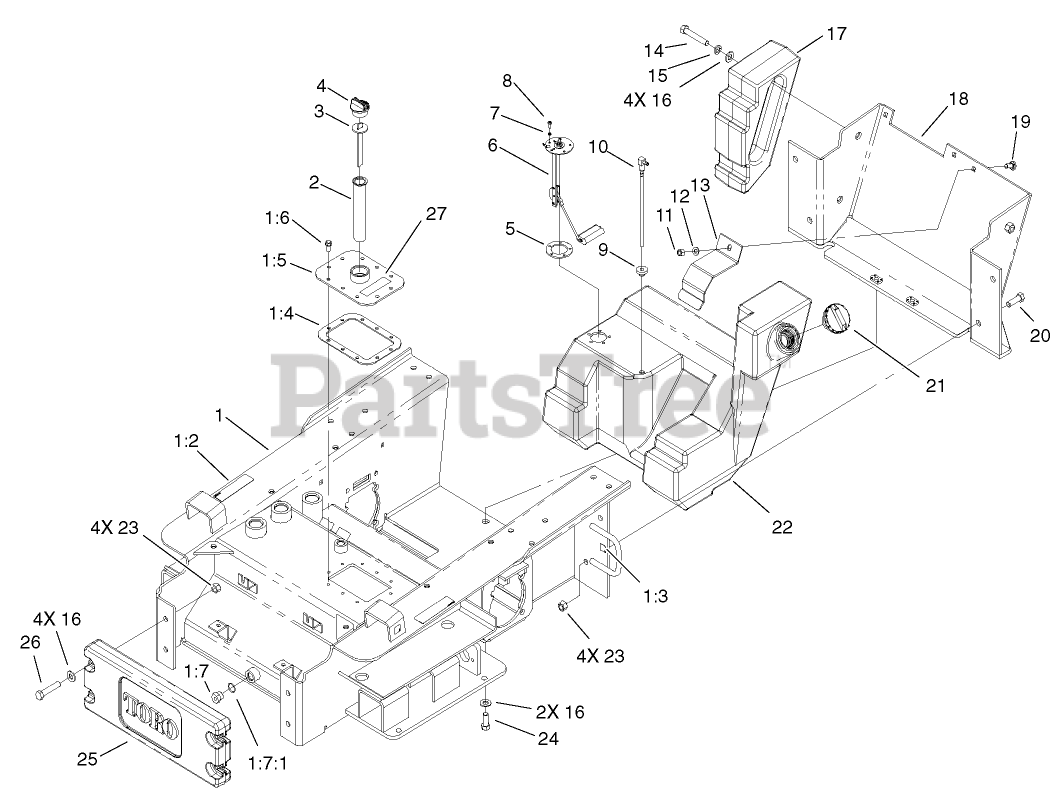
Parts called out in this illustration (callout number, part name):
1	CHASSIS ASM
1:2	DECAL-PINCH
1:3	DECAL-POINT, LIFT
1:4	GASKET-COVER, ACCESS
1:5	TANK COVER ASM
1:6	SCREW
1:7	PLUG-HEX
1:7:1	O-RING
2	FILTER-SCREEN
3	DIPSTICK-OIL
4	PLUG-PLASTIC
5	GASKET-SENDER, FUEL
6	SENDER-FUEL
7	WASHER-LOCK
8	SCREW-PPH
9	BUSHING
10	PIPE-STAND
11	NUT-LOCK, NI
12	WASHER-FLAT
13	CLAMP-TANK, FUEL
14	SCREW-HH
15	WASHER-LOCK
16	WASHER-FLAT
17	COUNTERWEIGHT-REAR
18	REAR FRAME COVER ASM
19	SCREW-CARR
20	SCREW-HH
21	CAP-FUEL
22	TANK-FUEL
23	NUT-LOCK, NI
24	SCREW-HH
25	COUNTERWEIGHT-FRONT
26	SCREW-HH
27	DECAL-OIL, HYD
